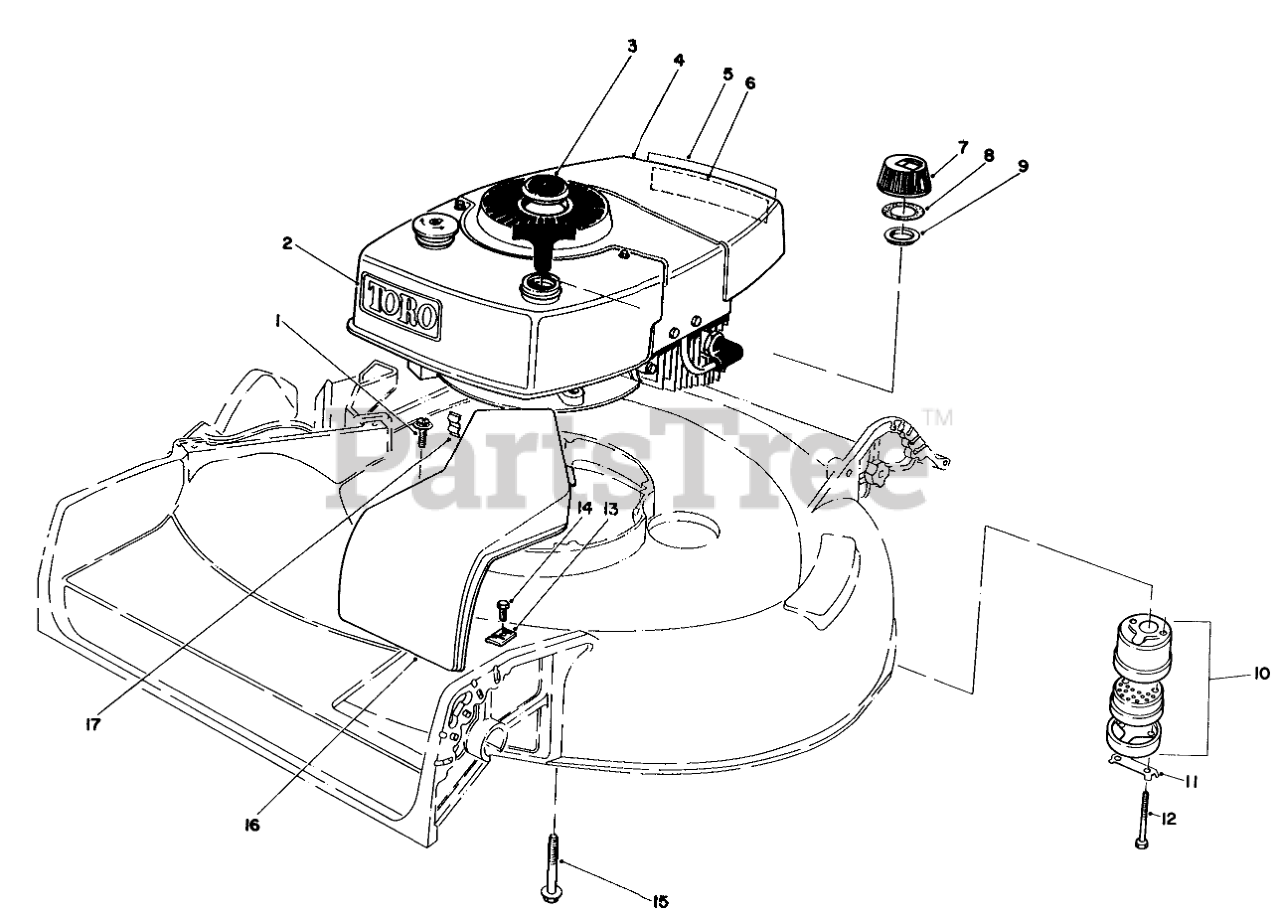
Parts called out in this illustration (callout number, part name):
1	Screw-Thread Forming
2	Decal Tow
3	Plug Button
4	Engine
5	Decal-Primer
6	Decal Maintenance
7	Fuel Cap Assembly (Incl. Ref. #8 & 9)
8	GASKET
9	GAS CAP BAFFLE
10	Muffler Assembly (Incl. Ref. #11 & 12)
11	CLIP - LOCKING
12	SCREW-HH
13	Cable Clamp
14	SCREW-HWHTF
15	3/8-16 X 2-3/4 CAPSCR
16	Cow-Belt
17	Clip Conduit
